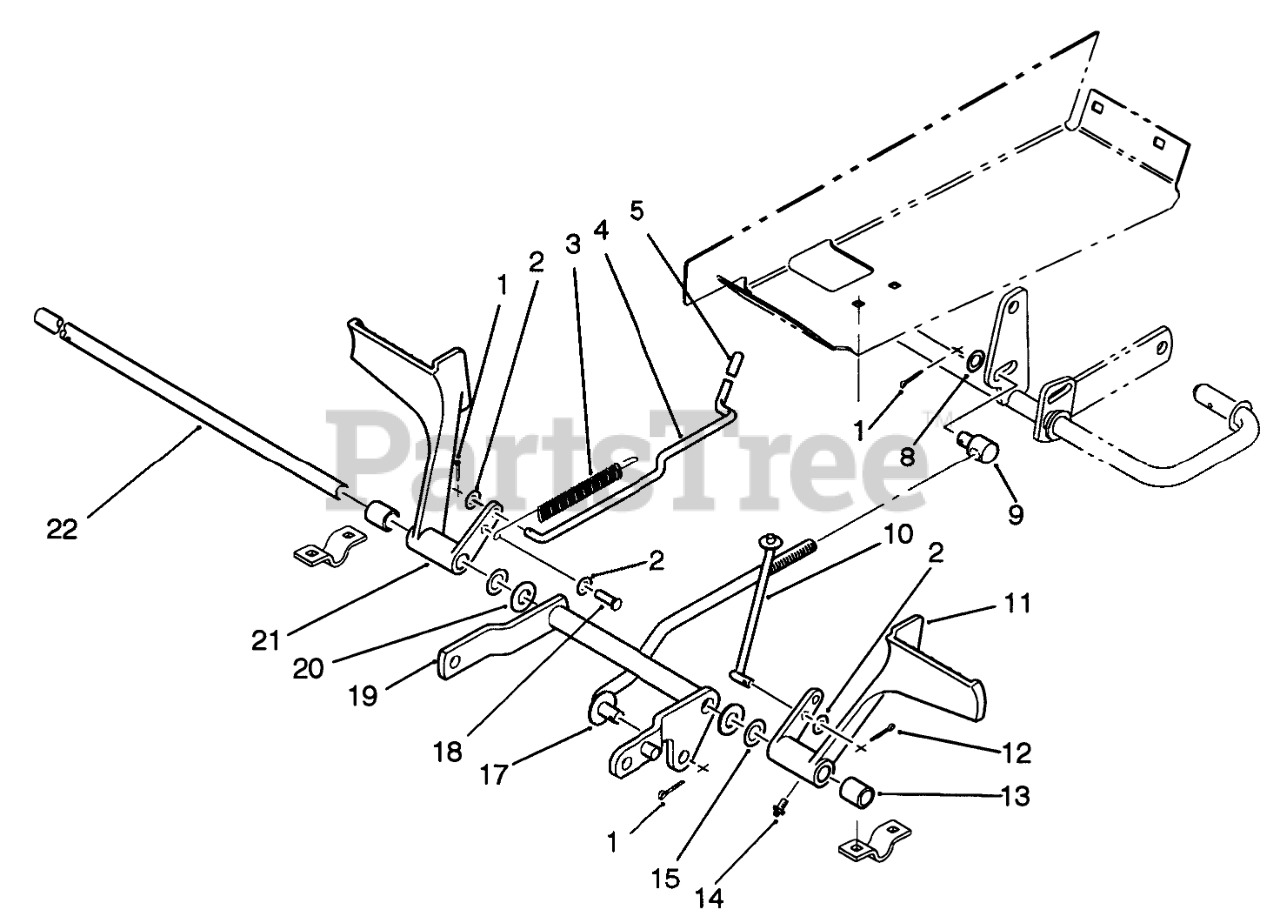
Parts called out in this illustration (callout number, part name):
1	PIN-COTTER
2	NUT-LOCK, NI
3	SPRING-BRAKE
4	ROD-BRAKE LOCK
8	WASHER-FLAT
9	ROD-TRUNNION LIFT
10	WLDMT-ROD B
11	Pedal-Clutch
12	PIN-COTTER
13	SPACER
14	Fitting-Grease
15	WASHER-WAVE
18	Pin-Clevis
19	Arm
20	Washer
21	Pedal-Brake
22	SHAFT
